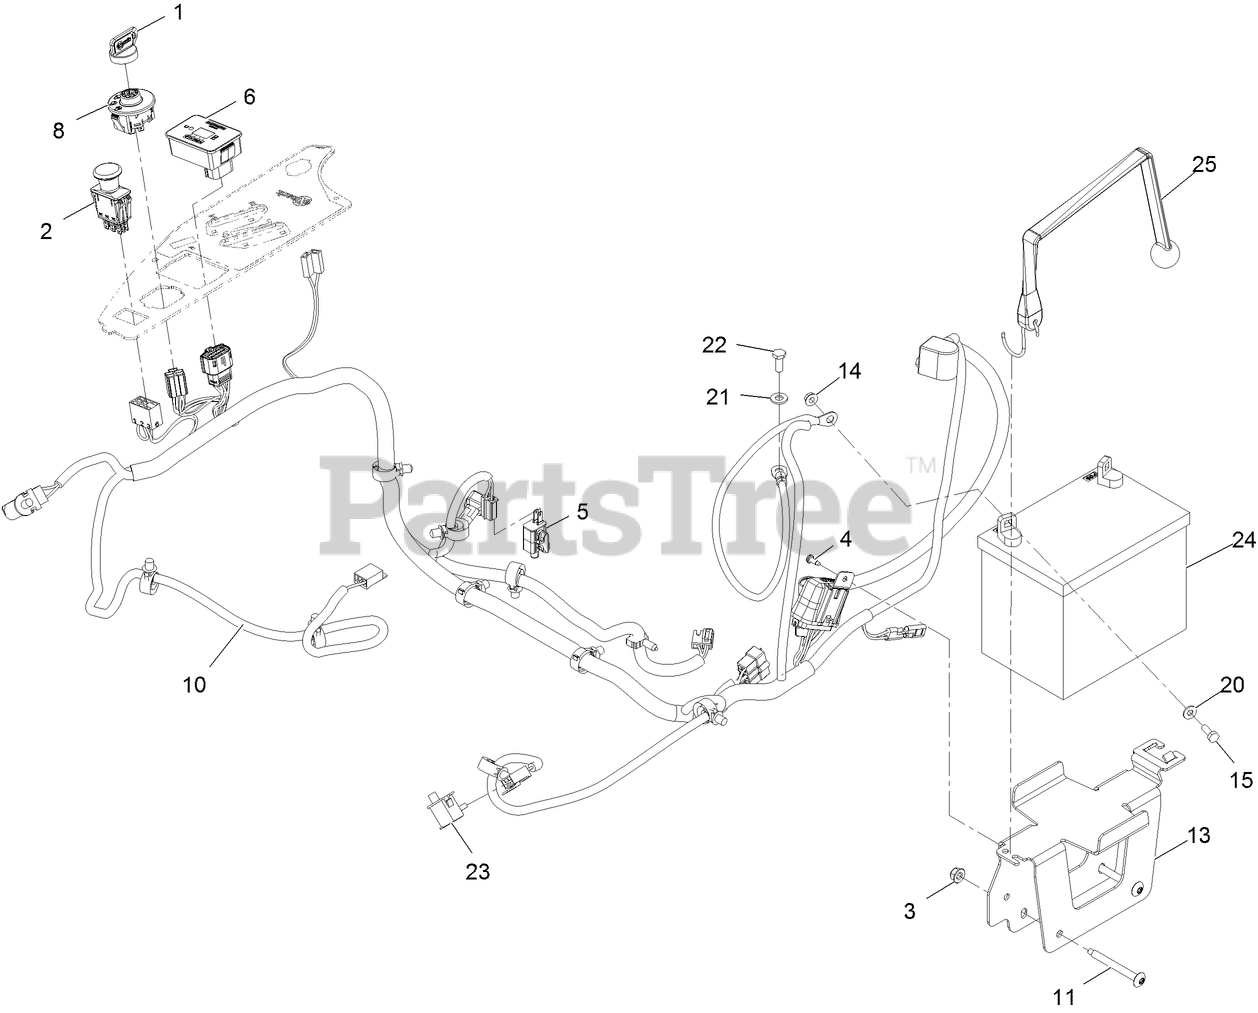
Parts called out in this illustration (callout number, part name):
1	KEYS-IGNITION (SPARE PAIR
1	KEY-IGNITION
2	SWITCH-PTO
3	NUT-HF, NI
4	SCREW-FORMING, THREAD
6	MODULE ASM
8	SWITCH-IGNITION
10	HARNESS-WIRE
11	SCREW-TORX
13	TRAY-BATTERY
15	SCREW-HH
20	WASHER-FLAT
21	WASHER-PLAIN
22	SCREW-HH
23	SWITCH-BAIL
24	Battery
25	STRAP-BUNGEE
